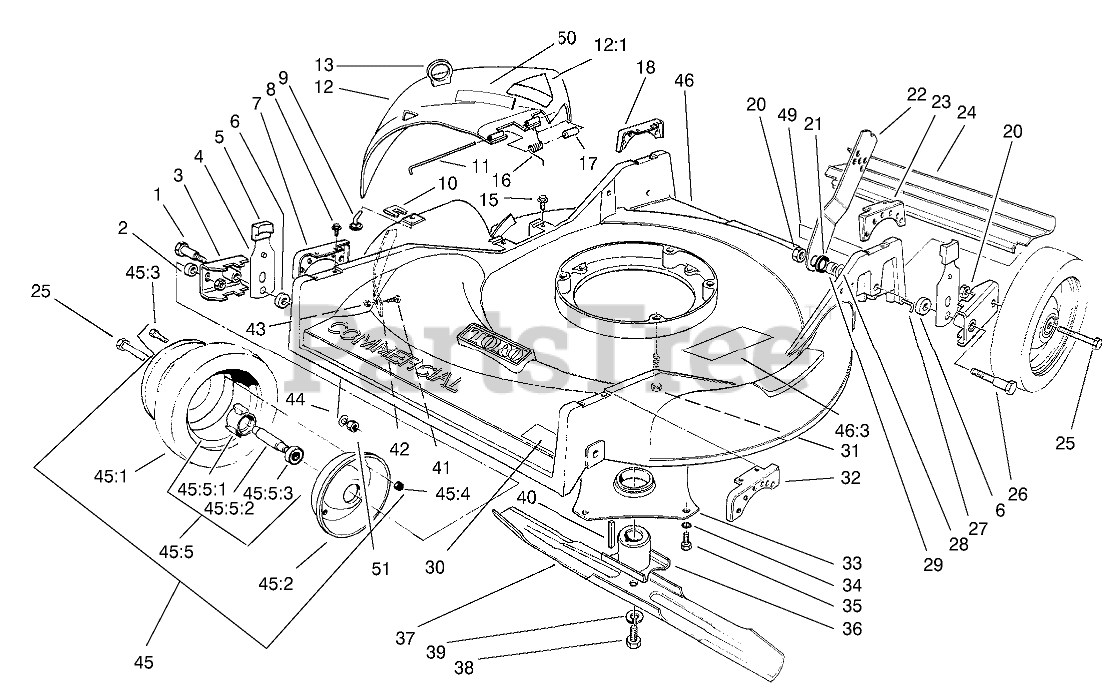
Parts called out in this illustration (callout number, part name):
1	PIVOT SCREW
2	SPACER-WHEEL
3	PIVOT ARM
4	SPRING ARM ASM-FRONT
5	KNOB-ARM
6	SPACER-PIVOT
7	FRT RIGHT QUAD
8	SCREW-HWHTF
9	BAG CHUTE PIN
10	BAG CHUTE CLIP PIN
11	DEFLECTOR HINGE PIN
12	DEFLECTOR
12:1	DECAL-DANGER
13	LIFT LOOP
15	SCREW-HWH
16	DEFLECTOR SPRING
17	SLEEVE
18	REAR RIGHT QUAD
20	NUT-LOCK, NI
21	HANDLE LATCH SPACER
22	LATCH-HANDLE
23	REAR LEFT QUAD
24	SHIELD - TRAILING
25	SCREW-HH
26	REAR PIVOT SCREW
27	SHIELD ROD
28	WASHER-BELLEVILLE
29	HANDLE LATCH SPACER
30	DECAL-BLADE
31	SCREW-HHF
32	FRT LEFT QUAD
33	CRNKSHFT PROTECT ASM
34	WASHER-LOCK, INTERNAL
35	SCREW-HWHTF
36	RETAINER-BLADE
37	Blade
38	SCREW-HH
39	WASHER-LOCK
40	KEY-SQUARE
41	SCREW-CARR
42	SAFETY BAR (RED)
43	NUT-LOCK, NI
44	WASHER-BELLEVILLE
45	WHEEL AND TIRE ASM
45:2	PLATE-WHEEL, HALF
45:3	SCREW-HH
45:4	NUT-LOCK, NI
45:5	HUB and BEARING ASM
45:5:1	Label-Emissions
45:5:2	SPACER-BEARING
45:5:3	BEARING-WHEEL
46	21 COMM SD HSG/DECAL
46:3	DECAL-WARNING
49	DECAL-WARNING
50	DECAL-DANGER DEFLECTOR
51	NUT-LOCK, CONE
